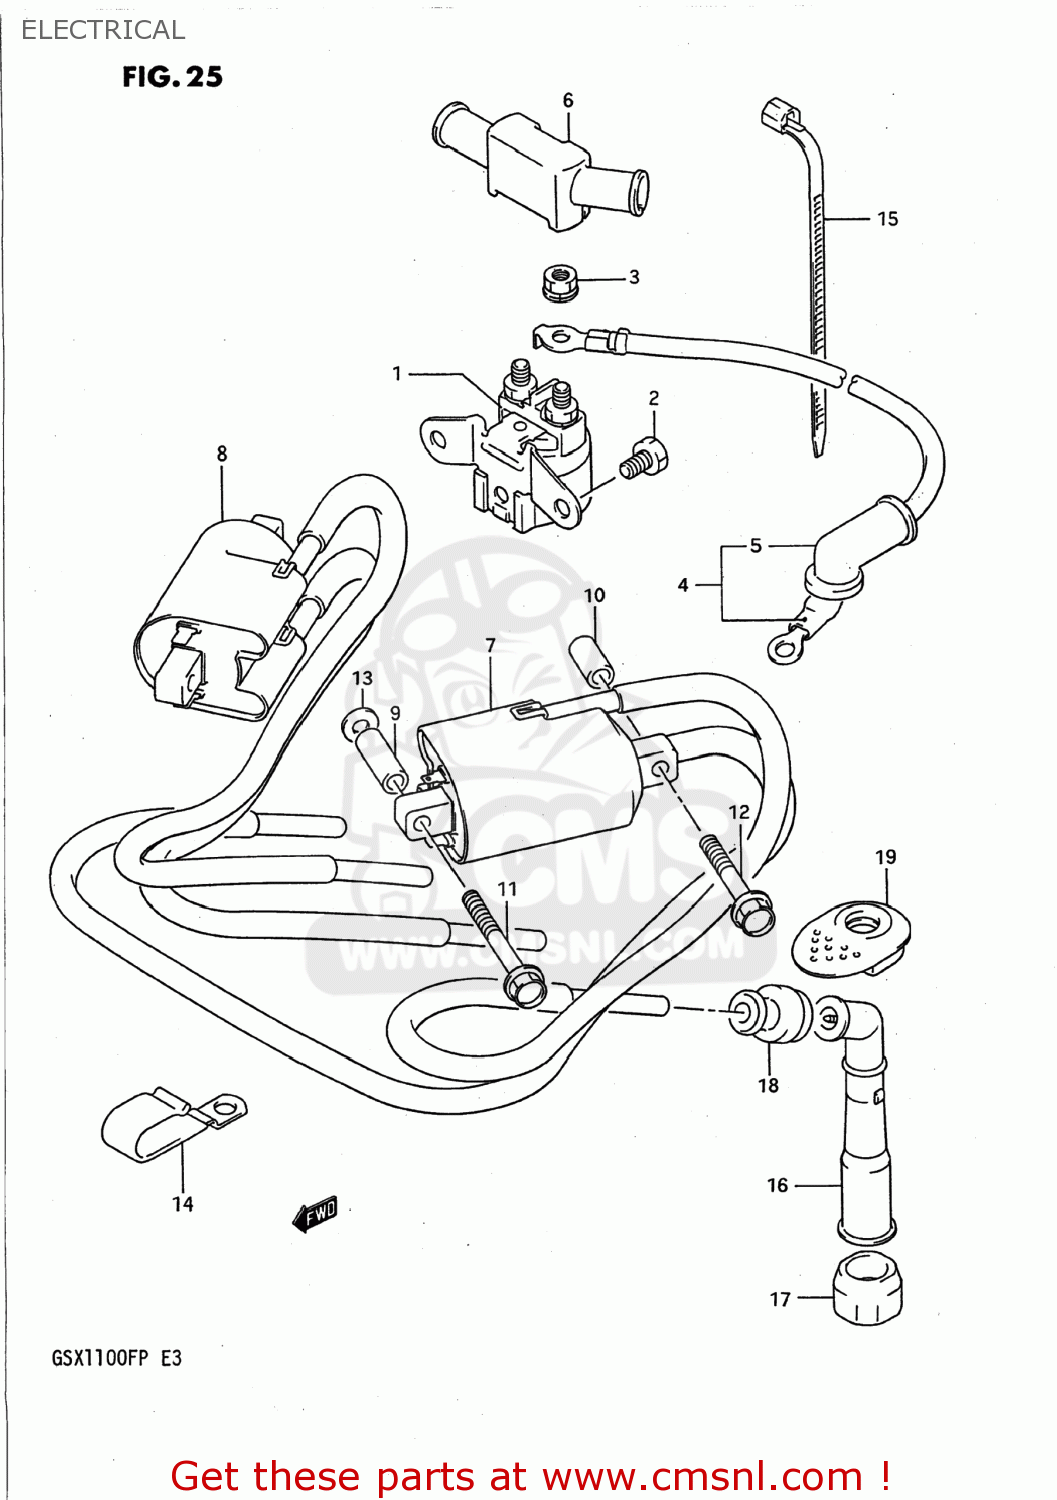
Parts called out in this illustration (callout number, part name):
1	RELAY ASSY,STARTING MOTOR
2	SCREW(6X8)
3	NUT
4	WIRE,STARTER MOTOR LEAD
5	CAP,STARTER MOTOR LEAD
6	CAP,STARTER RELAY
7	COIL ASSY,IGNITION
8	COIL ASSY,IGNITION
9	SPACER(6.4X10X28)
10	SPACER(6.4X10X18)
11	BOLT 6X50
12	BOLT 6X40
13	WASHER, LOWER
14	CLAMP
15	CLAMP(L:125)
16	CAP,SPARK PLUG
17	SEAL,SPARK PLUG
18	SEAL,HIGH TENSION CORD
19	COVER,SPARK PLUG CAP
